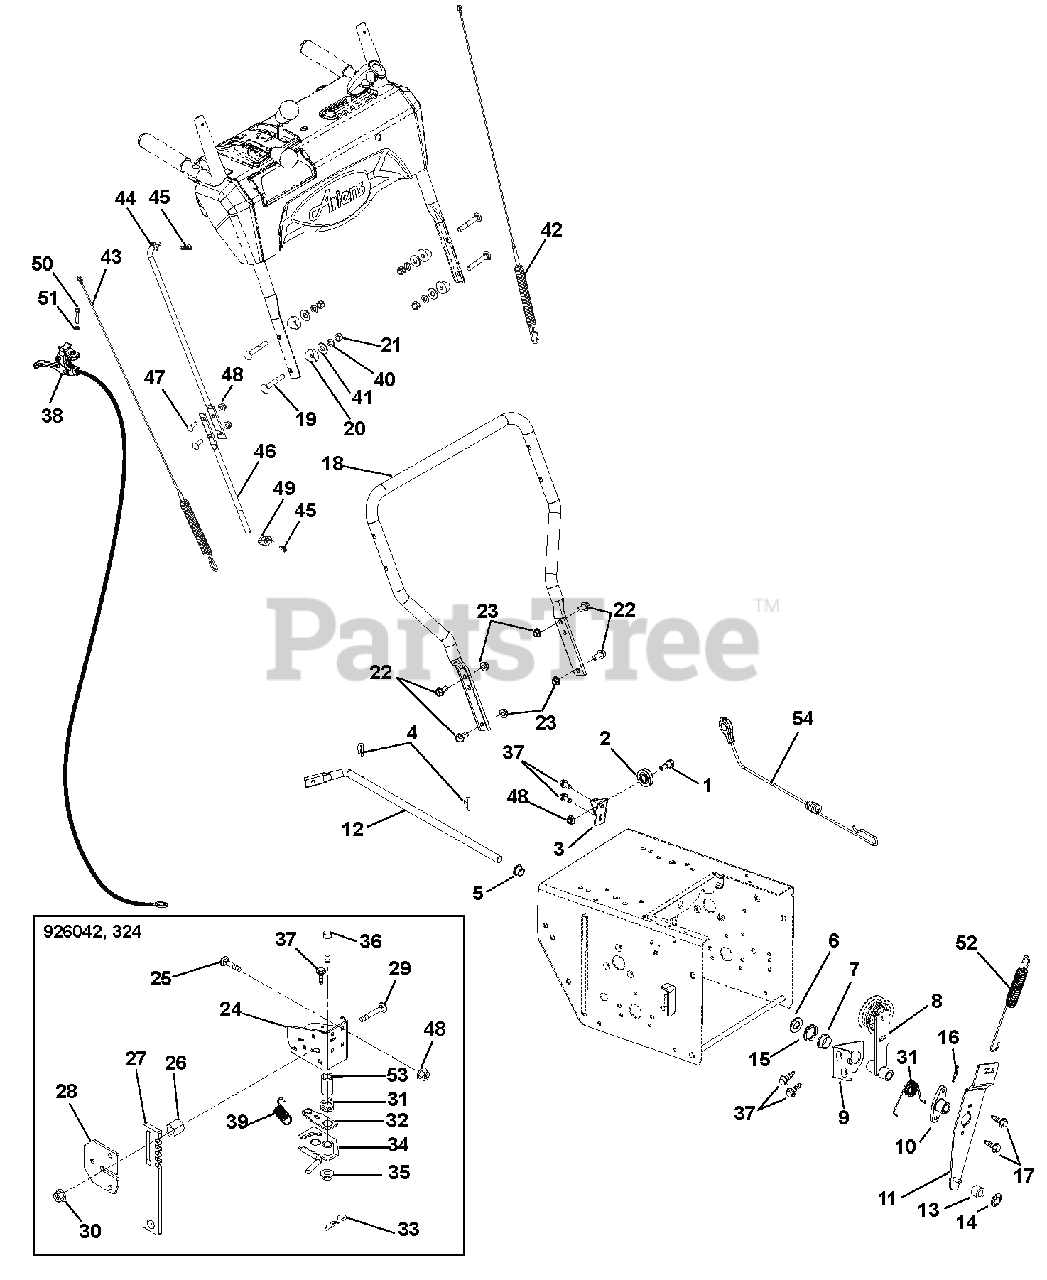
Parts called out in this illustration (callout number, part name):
1	BOLT, SHLDR-.375X.375X.25-20
2	PULLEY, CABLE
3	BRACKET, CABLE PULLEY
4	CLIP, SPRING
5	BUSHING, POLYLINER-.50 SPLIT
6	@WSHR-FL-STL.531X1.06X.095YWZC
7	BSHG,FLANGE .500X.625X.270X.75
8	ARM, IDLER-TRACTION
9	BRACKET, SUPPORT
10	HUB, BRAKE ARM
11	ARM, IDLER-ATTACHMENT
12	ARM, ATTACHMENT
13	BSHG,SLV .265 X .625 X .375
14	RG-RTNG-EXT .250X.010
15	WAVE SPRING .600X.875X.25FH
16	PIN-ROLL .125X1.00
17	SCR-TAP .25-20X.75 HWH TR YWZ
18	HANDLEBAR, LOWER
19	@BLT-RDHDSQNK .31-18X2.25 G5YZ
20	SPACER, HANDLEBAR
21	@NUT-LK-NYL .312-18 YWZC
22	BLT-SERHFWH .38-16X.75 YWZC
23	@NUT-LK-TOP-FLG .38-16 YWZC
24	BRACKET, HEIGHT ADJUSTER-PRO
25	@BLT-RDHDSQNK .25-20X.75 G5YZ
26	SPACER .50 X .32 X .42
27	STOP, HEIGHT ADJUSTER-PRO
28	PLATE, HEIGHT ADJUSTER
29	@BLT-RHDSHSQNK.31-18X1.25 G5YZ
30	@NUT-LK-TOP-FLG .31-18 YWZC
31	SG-TORS .067X.88
32	ARM, OVERTRAVEL
33	PIN-HAIR INT .06X.18X.77
34	LOCK, HEIGHT ADJUSTER
35	NUT-LK-CTR-FLG .38-16 YWZC
36	@BLT-HEX .38-16X1.75 GR5 YWZC
37	SCR-TAP .25-20X.50 HWH TR YWZ
38	CABLE, TRACK REMOTE
39	SPRING-EXT .047 X .438 X 1.85
40	WSHR-LK .312X.097 HVY YWZC
41	@WSHR-FL-STL.38X.875X.083 YWZC
42	CABLE, UPPER TRACTION
43	CABLE, AUGER (DELUXE & PRO)
44	ROD, SHIFT - UPPER
45	PIN-HAIR INT .08X.18X1.18 YWZC
46	ROD, SHIFT - LOWER
47	@BLT-RDHDSQNK .25-20X.75 G5YZ
48	@NUT-LK-CTR-FLG .25-20 YWZC
49	PIVOT,SHIFT ROD .375-16(TRUNN)
50	SCR-MCH .25-20X1.50 OVAL HD
51	WSHR-LK-INT .250 TH TYA
52	SG-TENS .06X.482X5.35
53	BSHG-SLV .385X.500X1.045
54	CABLE, LOWER TRACTION,SS & PRO
